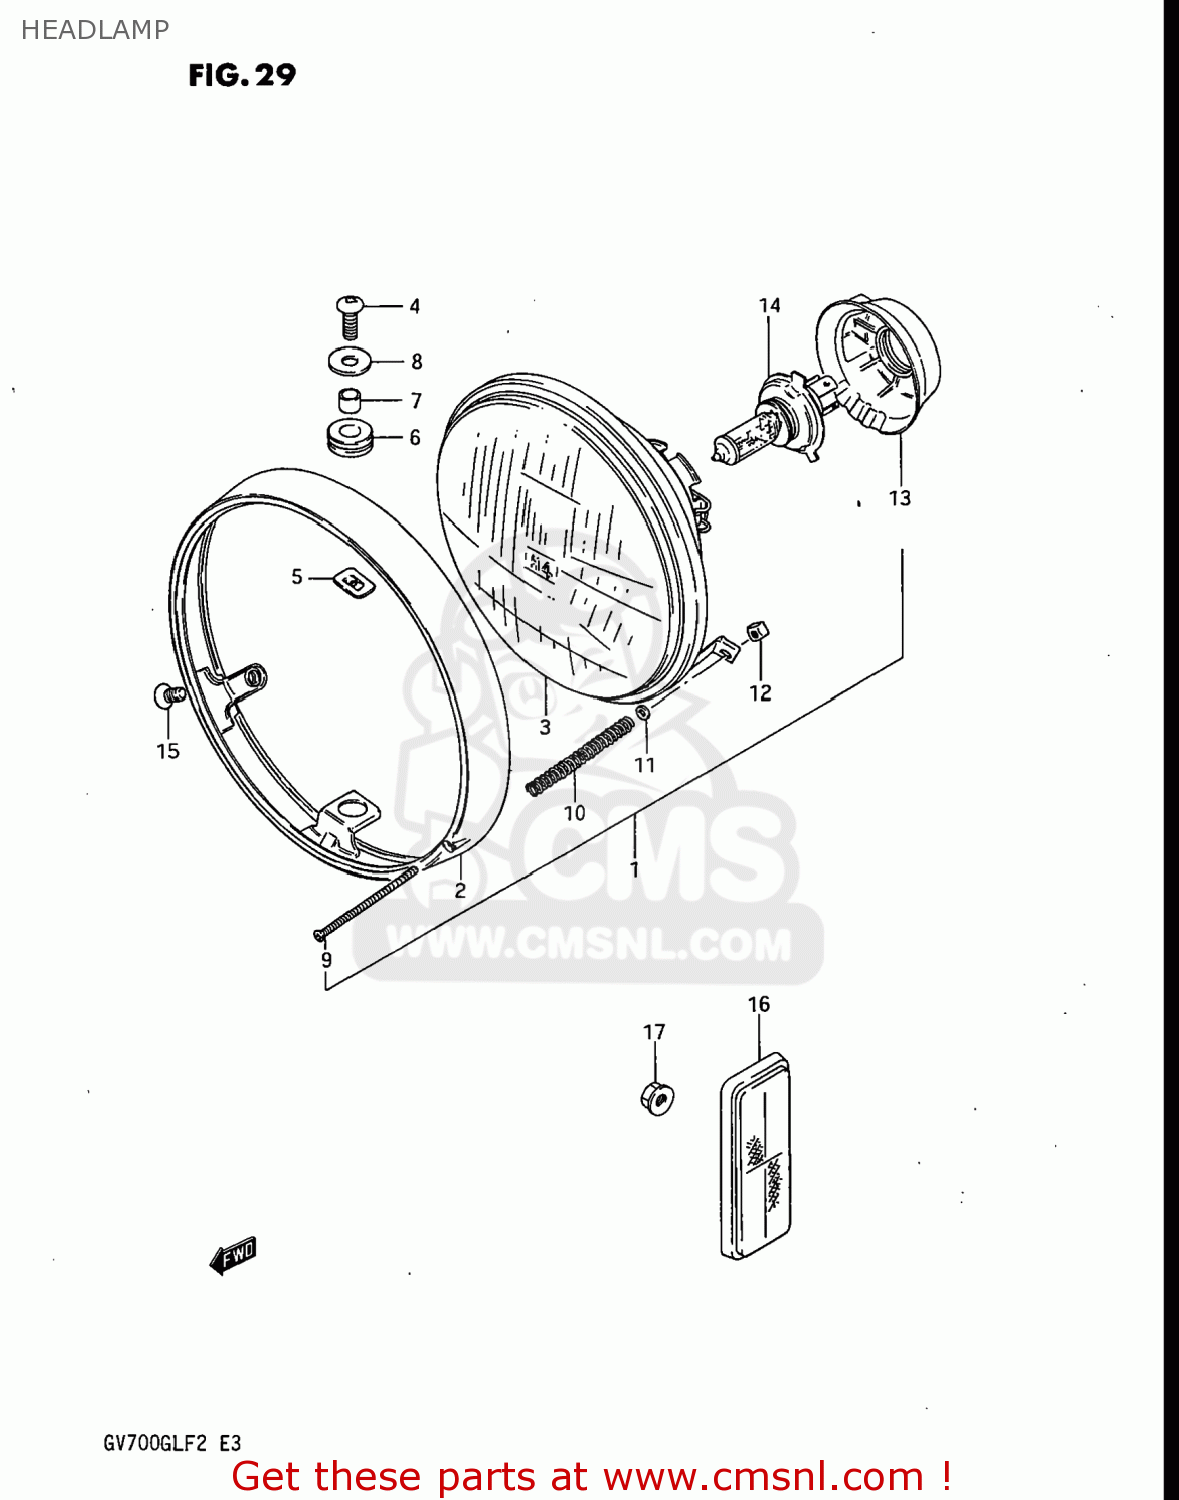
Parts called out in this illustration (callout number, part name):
1	HEADLAMP ASSY
2	RIM,HEAD LAMP
3	LAMP UNIT
4	SCREW(5X14)
5	NUT
6	CUSHION
7	SPACER
8	WASHER
9	SCREW,HEADLAMP ADJUST
10	SPRING,HEADLAMP ADJUST
11	WASHER
12	NUT
13	COVER,SOCKET
14	BULB(12V60/55W,H4)
15	SCREW(5X12)
16	REFLEX REFLECTOR,FR SIDE
17	NUT
